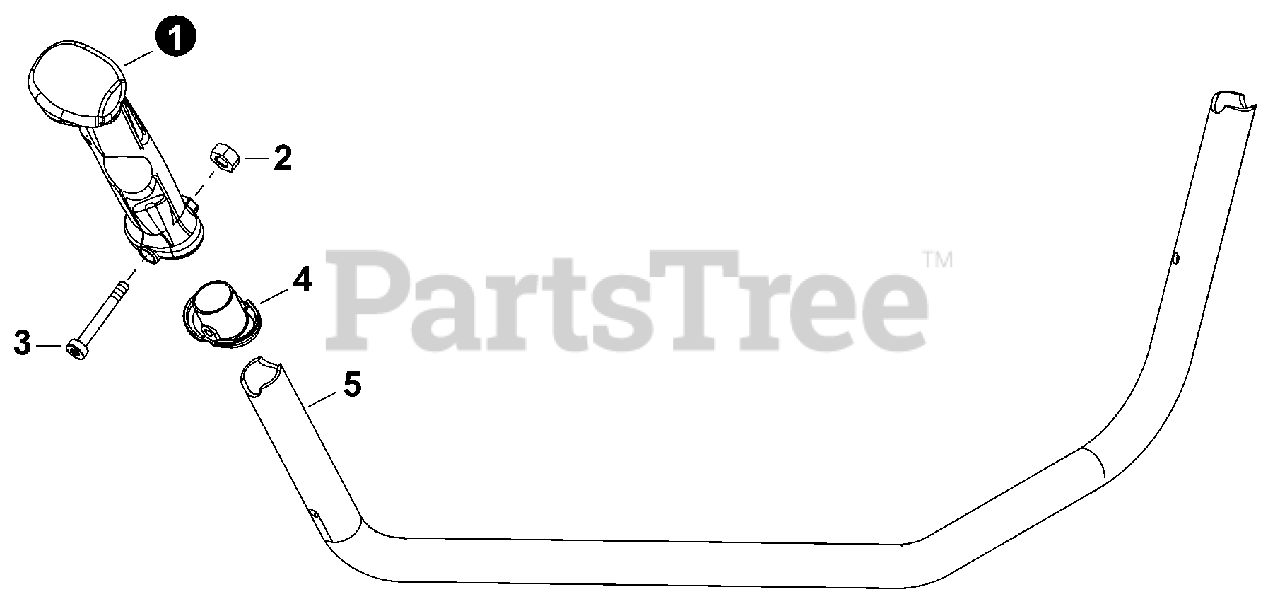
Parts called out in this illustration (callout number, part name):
1	GRIP, HANDLE
2	NUT, LOCK M5
3	BOLT, TORX 5x40
4	GUARD, HAND
5	U-HANDLE
